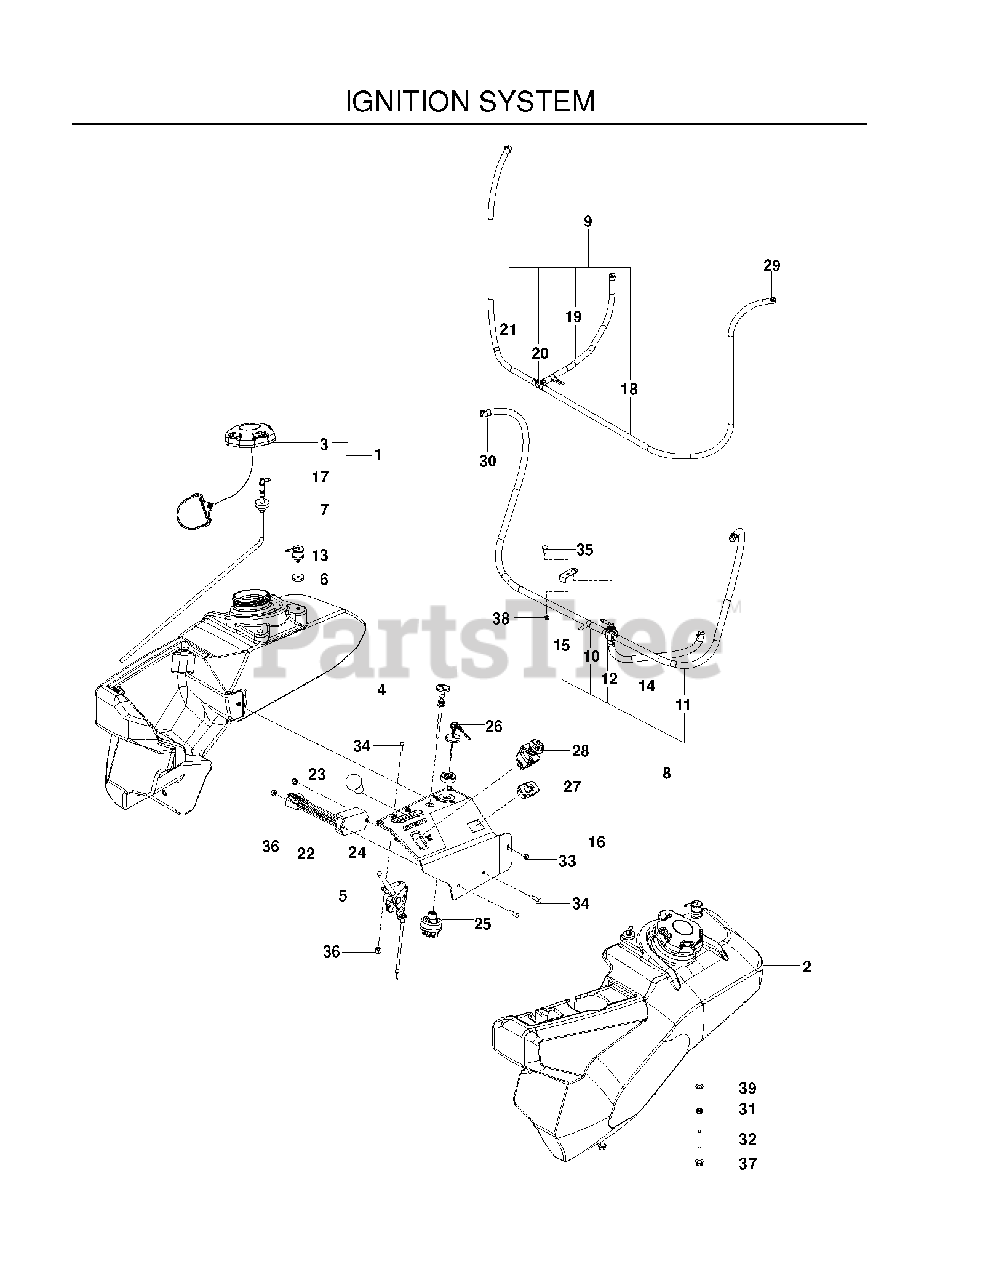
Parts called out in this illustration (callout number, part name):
3	CAP, FUEL
6	RUBBER GROMMET
7	GROMMET, CHECK VALVE
10	FUEL LINE - 2.5"
11	VALVE, CHECK, .25
12	FUEL VALVE
13	VALVE, FUEL CHECK
14	TEE, FUEL LINE, .25
15	FUEL LINE 29.5"
16	FUEL LINE
21	FUEL LINE 33"
22	TIMER, SEAT
23	KNOB - SHIFT
25	SWITCH, IGNITION, INDAK
26	KEY, IGNITION
27	HOUR METER
28	SWITCH, PTO 10 AMP
30	CLAMP, HOSE
31	HOSE CLAMP
33	STUD, 5/16C
34	SCR #10-24 X 3/8 SKT HD BLK OX
35	SCR #10-24 X .75 SKT HD BLK
36	FLAT WASHER 5/16 SAE
37	NUT 10-24 NYLOC
38	5/16-18 NYLOC FLANGE NUT
39	FLAT WASHER 5/16 SAE
